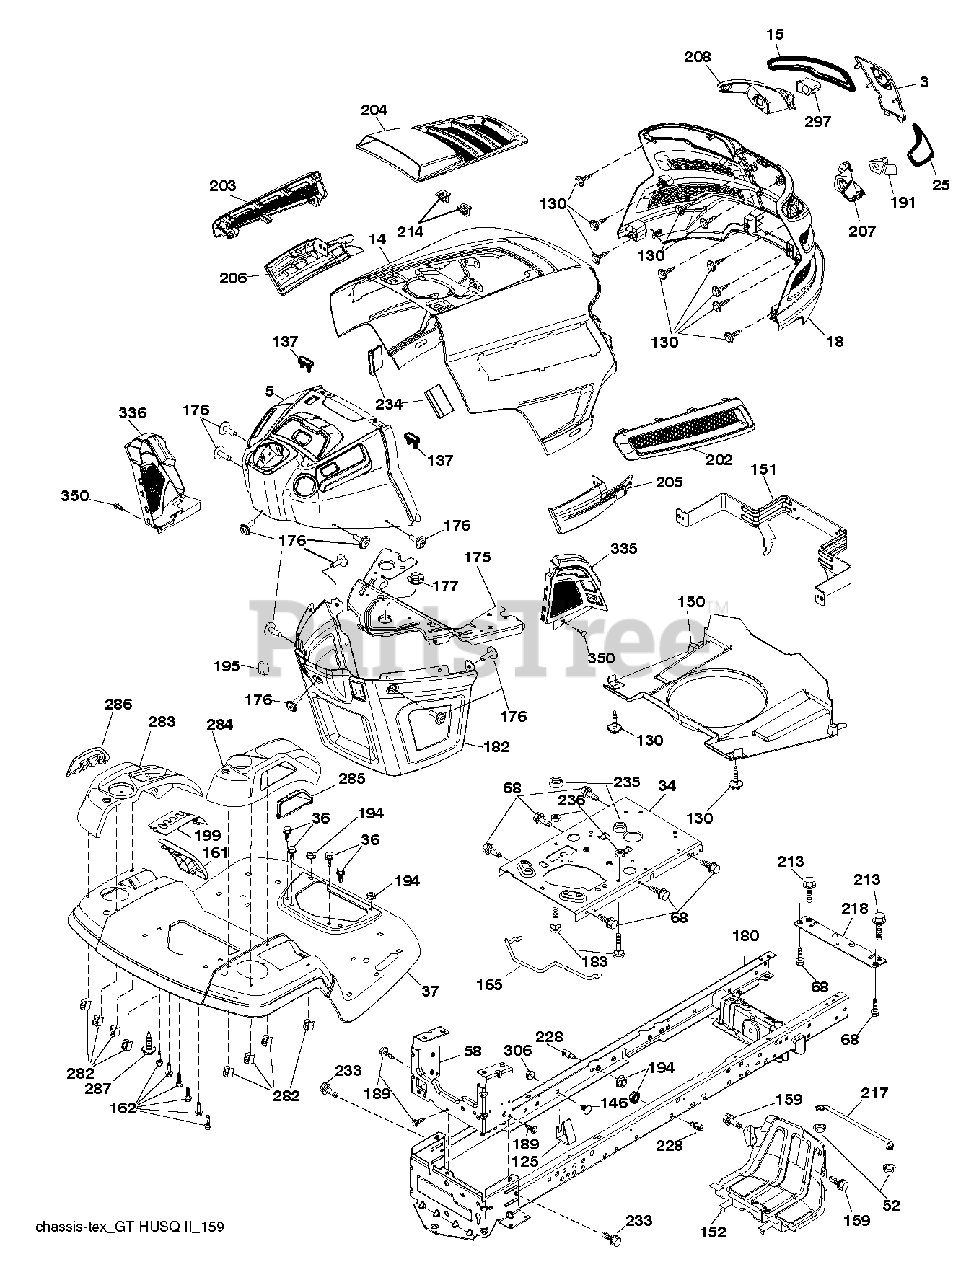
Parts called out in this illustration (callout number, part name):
3	APPLIQUE.SUBASM.GT.HUSQ.II
5	DASH.UPR.ASSY.GT2.SRVMNDER.PTO
14	DASH
15	LENS.HEADLIGHT.LH.GTII.2011
18	GRILLE.SUBSTRATE.2011.
25	LENS.HEADLIGHT.RH.GTII.2011
34	PLATE.ENGINE.WELDED.CHASSIS
36	SCREW 5/16"
37	FENDER.TLT.FS.W/CPH/FW/RSF.668
52	LOCKNUT
58	DRAWBAR UPPER 2PC SMALL FENDER
68	SCREW LT
125	CLIP.FUEL.LINE
130	SCREW.#10 X 0.750.BOS
137	BUMPER DASH
146	BOLT.RDHD.SHT.SQNK.3/8-16X5/8
150	AIR.DUCT.GTV.BLACK
151	BRACKET.PIVOT.HOOD.GT.HUSQ.II
152	SHIELD.BROWNING.PNT.GT.V2
159	SCREW, 3/8-16X3/4
161	WINDOW.FUEL.LT.HUSQ.TEX.498
162	SCREW.HI-LO.CONSOLE
165	SUPPORT.TANK.REAR.W/TEX
175	PLATE.CROSSMEMBER.HUSQ
176	SCREW.#10-24X5/8.RN.QU
177	BUSHING, STEERING
180	CHASS.WLDMNT.TL.12GA/2P.48/54
182	DASH.LOWER.COMMON.12V.ADAPTOR
183	BOLT.5/16-18X1-1/4 FULL THD
189	SCREW
191	INSERT.REFLECTIVE.RH.HUSQ.GTII
194	NUT LOCK HEX FLANGE 5/16-18
195	PLUG.HOLE.DASH.LOWER.12V.BLK
199	PLATE.DECK.LIFT.HUSQ.LT
202	VENT.SIDE.RH.GT.HUSQ.II.
203	VENT.SIDE.LH.GT.HUSQ.II.498
204	VENT.TOP.HUSQ.GT2
205	SIDE.TRIM.RH.GT.HUSQ.II
206	SIDE.TRIM.LH.GT.HUSQ.II.GRAY
207	BEZEL LIGHT.RH.GT.II.MYLAR
208	BEZEL LIGHT.LH.GT.II.MYLAR
213	BOLT
214	CLIP.RETAINER.TINNER.
217	ROD.PIVOT.HOOD
218	X-PIECE.HOOD.STOP.NON/
228	STUD.FASTNER.W/ANTI-ROTATE
233	BOLT.SHOULDER
234	BUMPER.HOOD.TEX.HUSQVARNA
235	SPACER FENDER
236	NUT.CENTERLOCK.5/16-
282	CLIP.RETAINER.CONSOLE.LT.HUSQ
283	CONCOLE.CNTRL.PDL.HUSQ.LT.498
284	CONSOLE.DECK.LIFT.R.SDFL.HUSQ
285	CONSOLE INSERT RH
286	CONSOLE.INSRT.LH.HUSQ.LT.BLACK
287	SCREW 1/4X20
297	INSERT.REFLECTIVE.LH.HUSQ.GTII
306	NUT LOCK FLG 3/8-16 UNC
335	COVER.LOWER.DASH.RH.BLACK
336	COVER-LH.LOWER.DASH.GT2.BLACK
350	CLIP.X-MAS.TREE
